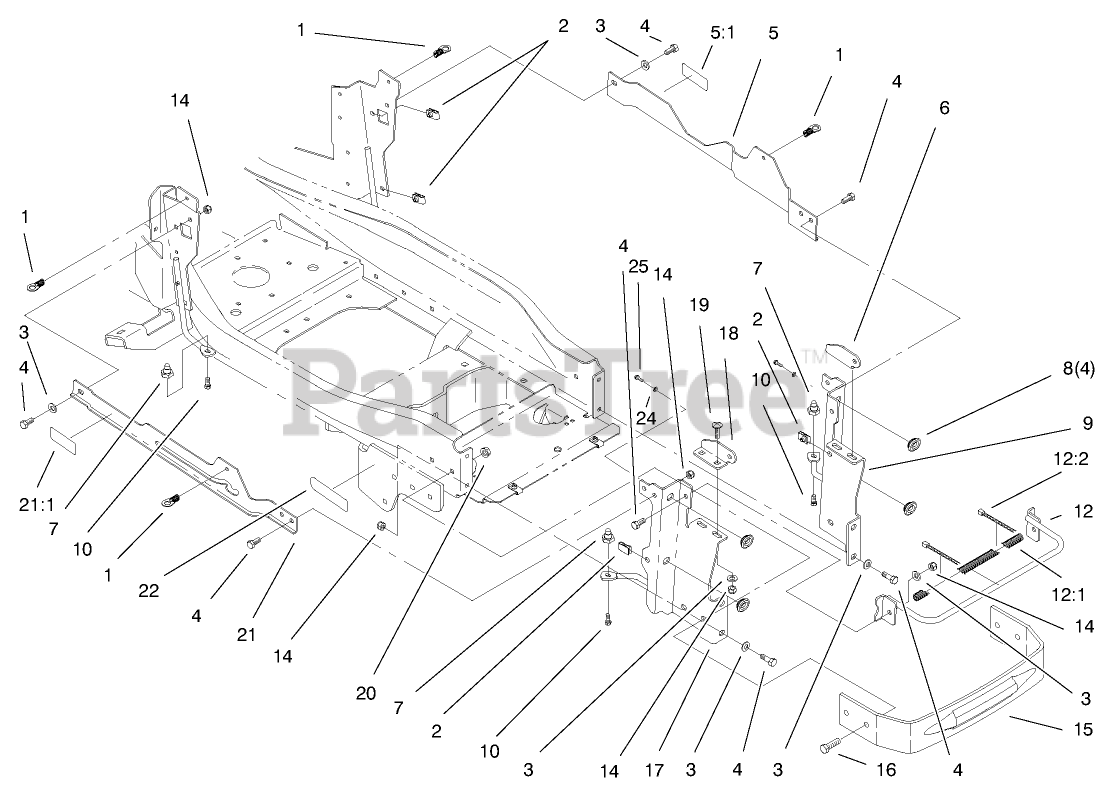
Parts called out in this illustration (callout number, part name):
1	LATCH ASM
3	WASHER-PLAIN
4	SCREW-HH
5	Support ASM (Only On: 73541)
5:1	DECAL-WARNING
5:1	DECAL - WARNING
6	BRKT-LOWER HINGE LH
7	MOUNT-SIDEPANEL
8	GROMMET
10	SCREW-PLASTITE
12	ASSEMBLY - HOOD SUPPORT
12:1	COVER-BRACE
12:2	TIE-CABLE
14	NUT-LOCK, NI
16	SCREW-HH
17	SUPPORT-HOOD, RH
18	BRACKET-LOWER HINGE RH
19	SCREW-CARR
20	NUT-LOCK, NI
21	Support ASM (Only On: 73541)
21:1	DECAL-WARNING
21:1	DECAL - WARNING
22	DECAL-ATTACH A-MATIC
24	WASHER-FLAT
25	SCREW-THD FORM, HWH
